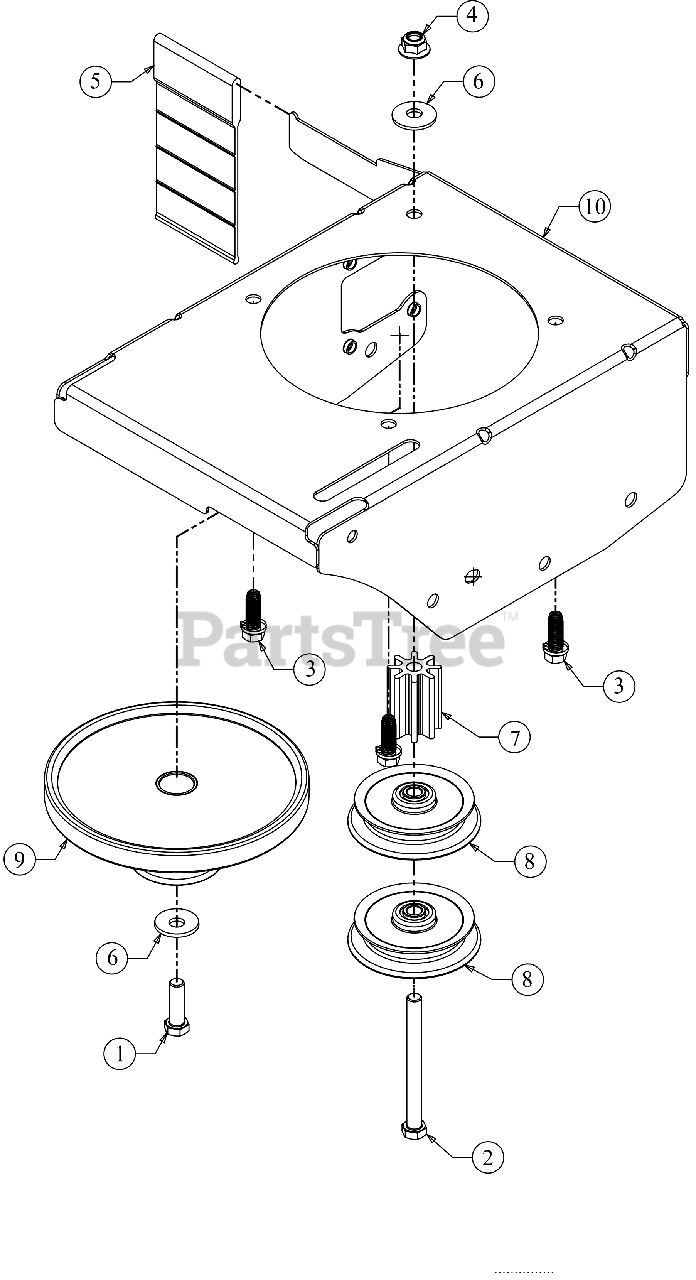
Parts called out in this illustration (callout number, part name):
1	SCREW 3/8-24X1.25
2	HEX SCREW 3/8-16 X 4.00
3	SCREW 3/8-16 X 1
5	EDGER BLADE GUARD
6	BELL WASHER
7	MOUNT SPACER
8	FLAT IDLER PULLEY
9	ENGINE PULLEY
10	EDGER FRAME
